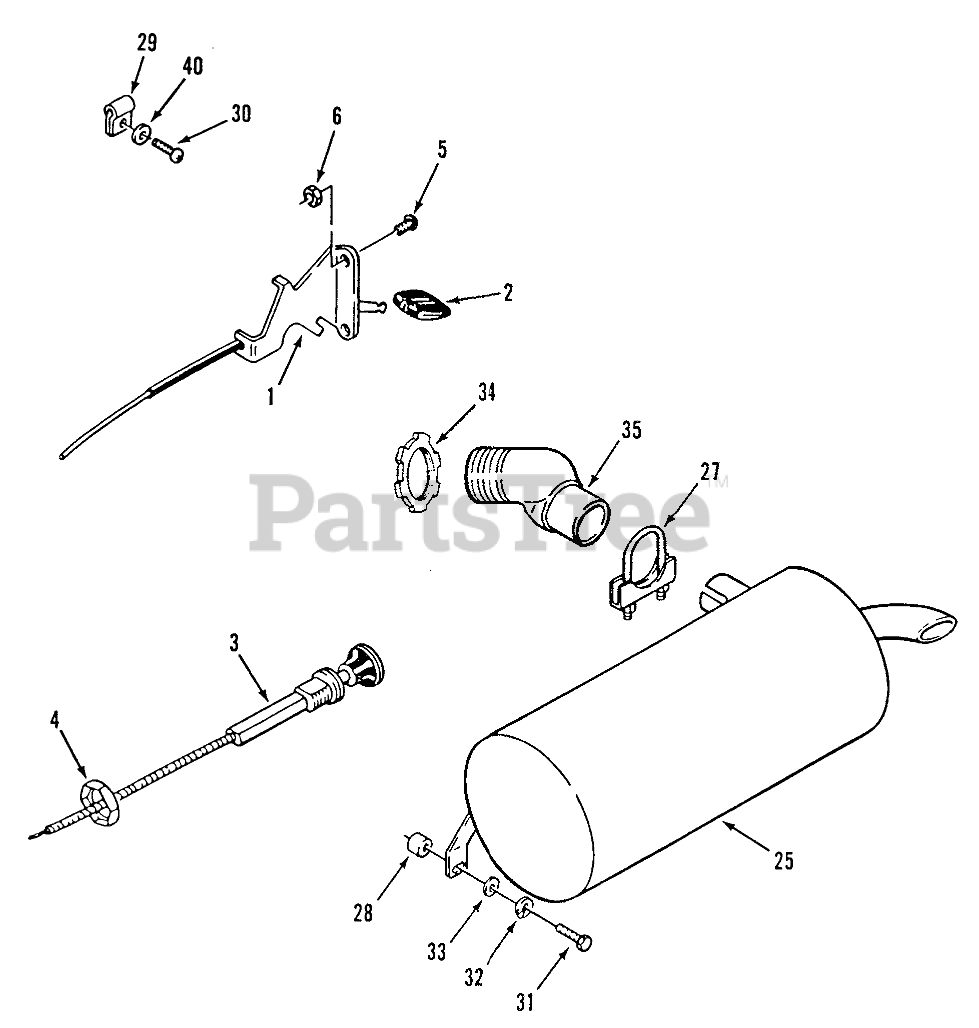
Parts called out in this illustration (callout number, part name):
1	Throttle Control 310, 312, 414
2	KNOB-THROTTLE
3	CONTROL CHOKE
4	NUT-HEX PALNUT
5	SCRW-PHC
6	Nut
25	Muffler
27	CLAMP-1 1/2
28	SPACER
30	Hex Wash. Hd. Screw 1/4-20 x 7/16 (vendor nr. X-67-83)
31	Bolt
32	Lockwasher
33	WASHER 5/16 SAE
34	Nut-Lock
35	Elbow
40	Washer
